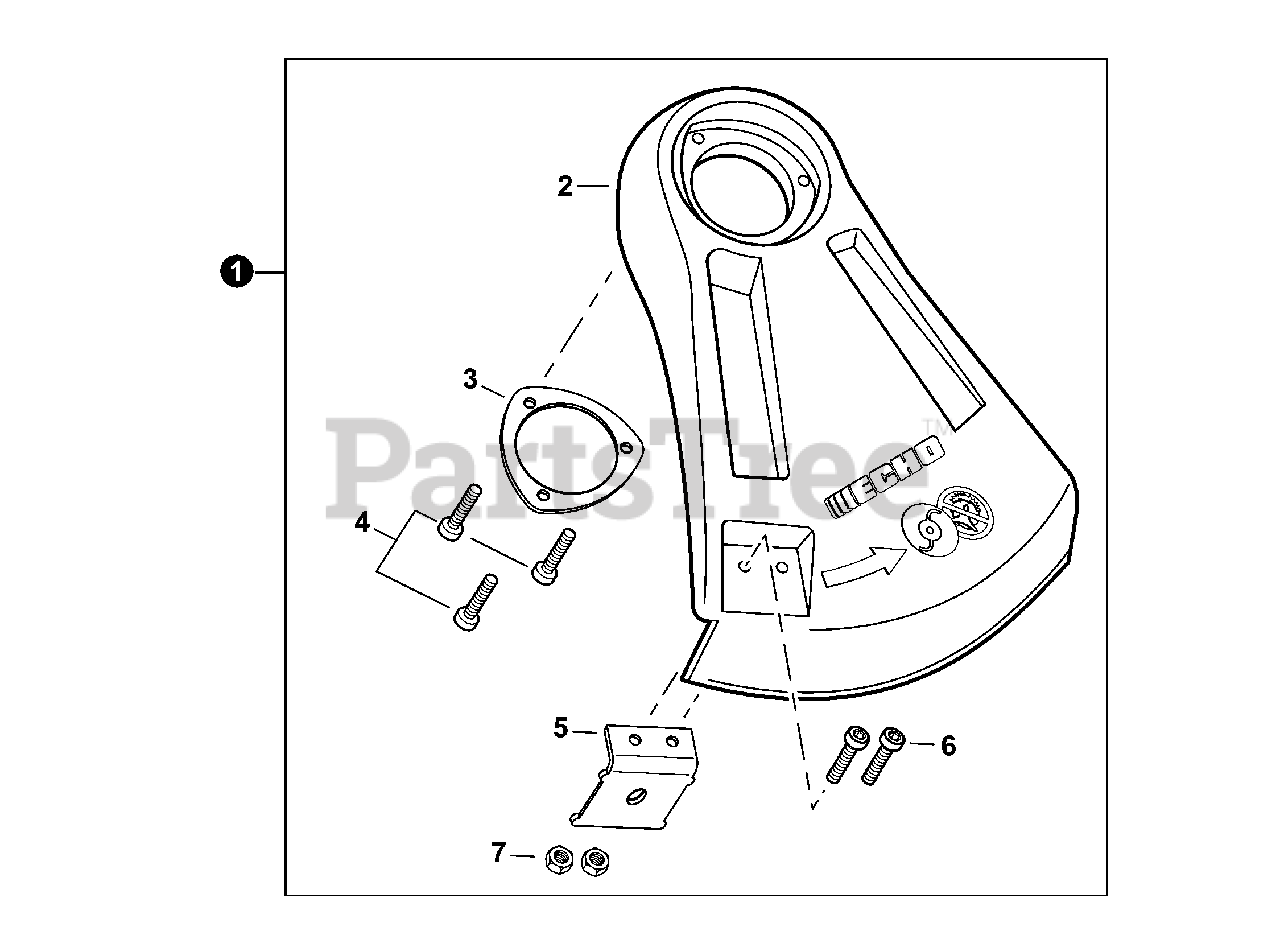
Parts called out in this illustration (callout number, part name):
1	DEBRIS SHIELD ASSY
2	SHIELD, DEBRIS
3	PLATE, SHIELD
4	BOLT, TORX 5×16
5	CUTTER, NYLON LINE
6	BOLT, TORX 5×12
7	NUT M5
